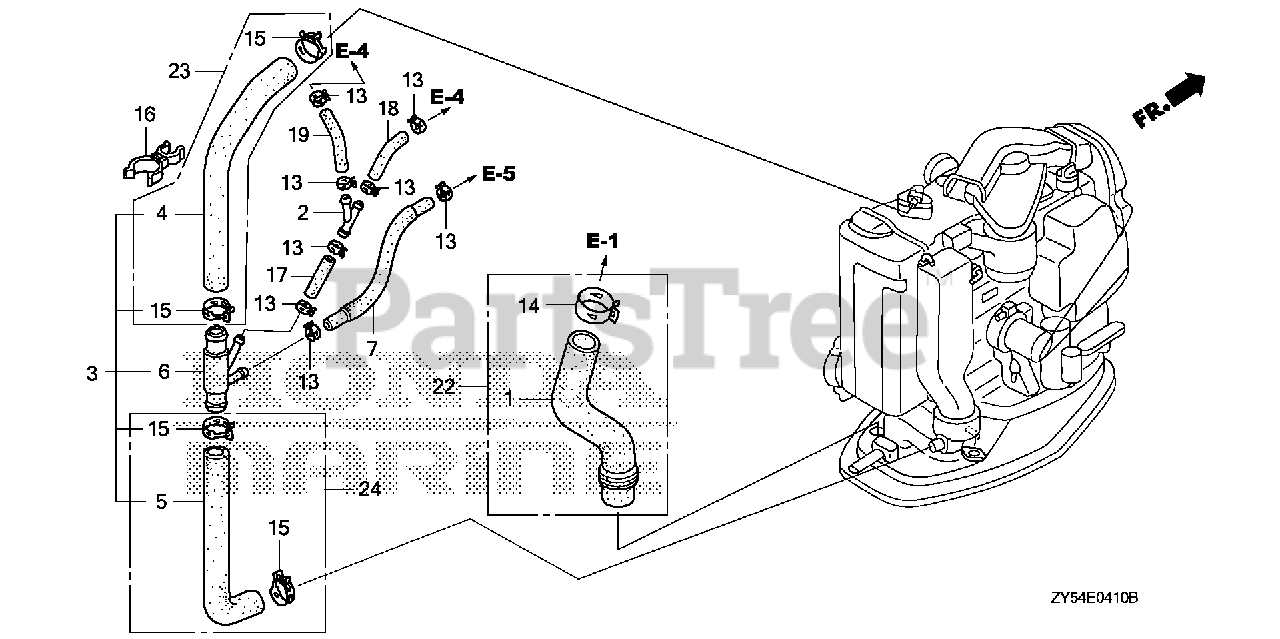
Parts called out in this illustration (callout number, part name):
1	TUBE, OIL
2	JOINT, FUEL TUBE
3	TUBE, WATER RELIEF
4	TUBE A, WATER RELIEF
5	TUBE B, WATER RELIEF
6	JOINT, FOUR-WAY
7	TUBE E, WATER
13	CLAMP, TUBE (D10.5) (ENGINE NO.)
14	CLAMP, TUBE (D32.5)
15	CLAMP, TUBE (D25.0)
16	CLAMP, WATER TUBE
17	BULK HOSE, VACUUM (7X3000) (7X550)
18	BULK HOSE, VACUUM (7X3000) (7X550)
19	BULK HOSE, VACUUM (7X3000) (7X550)
22	TUBE SET, OIL
23	TUBE SET A, WATER RELIEF
24	TUBE SET B, WATER RELIEF
